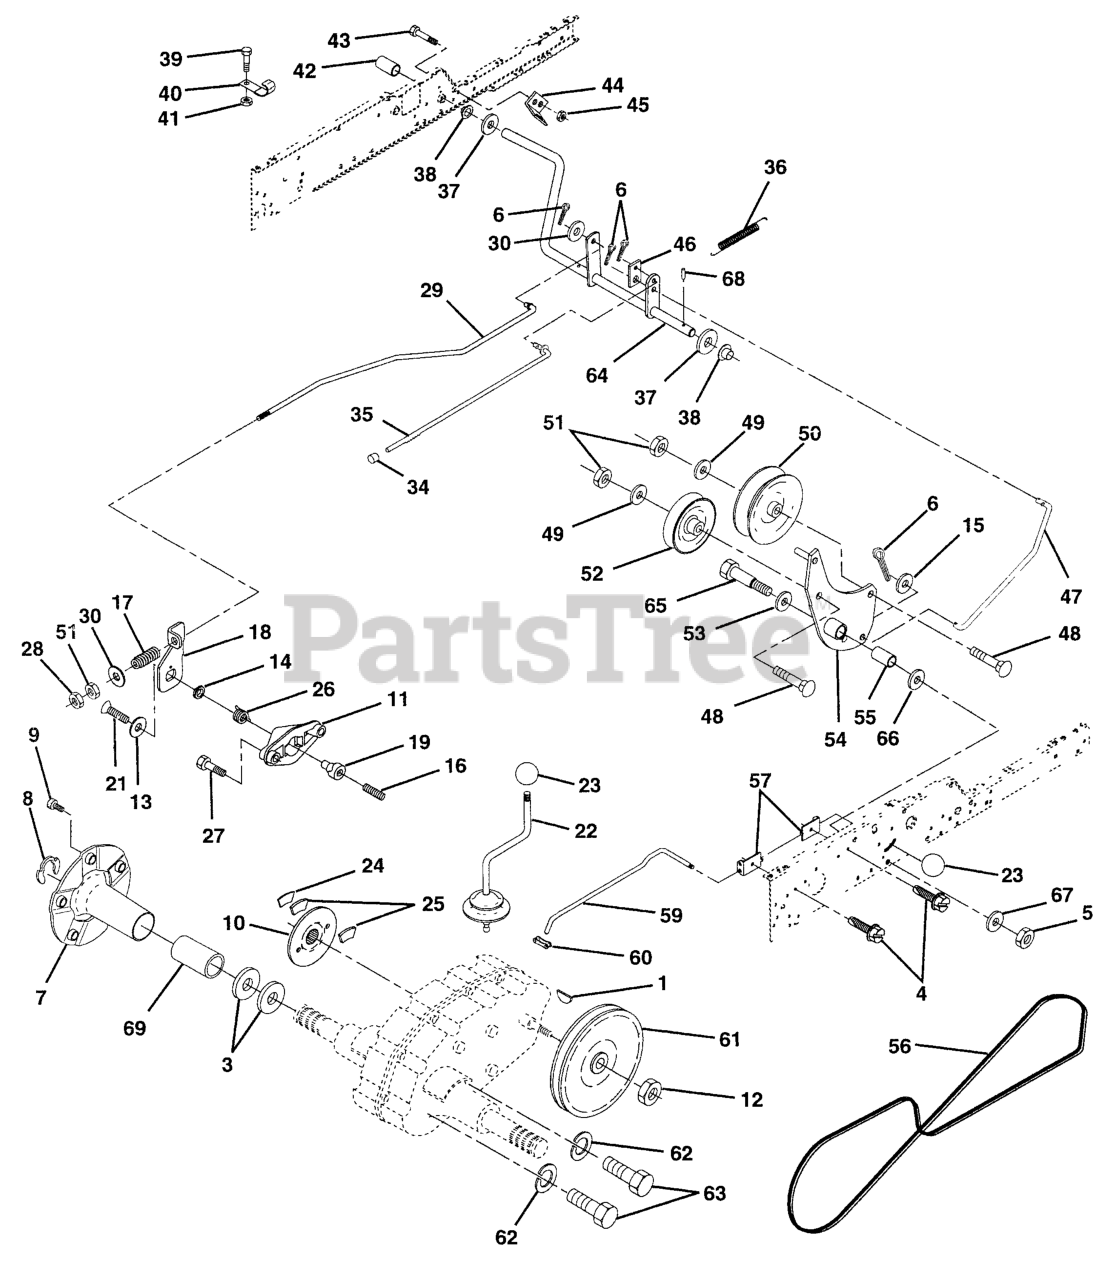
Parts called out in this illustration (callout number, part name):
1	KEY
4	Screw Thdrol 5/16-18 x 1/2 TYT
6	COTTER PIN
7	HUB.WHL.ASM.REAR
9	HUB BOLT
10	DISC BRAKE
11	YOKE-BRAKE DISC
15	WASHER
17	SPRING,ROD BRAKE
18	BRAKE LEVER
19	BRAKE DISC CAM
21	Screw Flat Head 1/4-28 x 3/4
22	GEAR SHFT LVR T
24	BRAKE PUCK SUPPORT
25	BRAKE PUCK TOP
26	RETURN SPRING
27	SCREW
28	NUT
29	ROD BRAKE ZINC GT
30	WASHER
34	PLUNGER CAP
35	PARKING BRAKE ROD
36	SPRING DRIVE GROUND
39	Screw Fin #10-24 x 1
40	ACT-SWITCH T
41	LOCKNUT
42	COVER, PEDAL (1 2)
43	BOLT.HEX.1/4.X.3/4.DICHROMATE
44	BRKT SWITCH GT
45	LOCKNUT.NYLOC.1/4-20
46	RETAINER SPRING
47	CLUTCH ROD
49	Washer 13/32 x 7/8 x 13 Ga
50	FLAT IDLER PULLEY
51	NUT
52	PULLEY.IDLER.V.
54	CLUTCH ARM ASSY
55	BEARING LT (2 2)
56	V-BELT GROUND DRIVE
57	BRACKET SHIFT ROD
59	ROD SHIFT HI LO
60	CONNECTING LINK
61	TRANSAXLE PULLEY
62	LOCKWASHER
63	BOLT
64	PEDAL SHAFT
66	WASHER.BLADE
67	WASHER
68	ROLL PIN STD
69	COVER.HUB.BLACK
